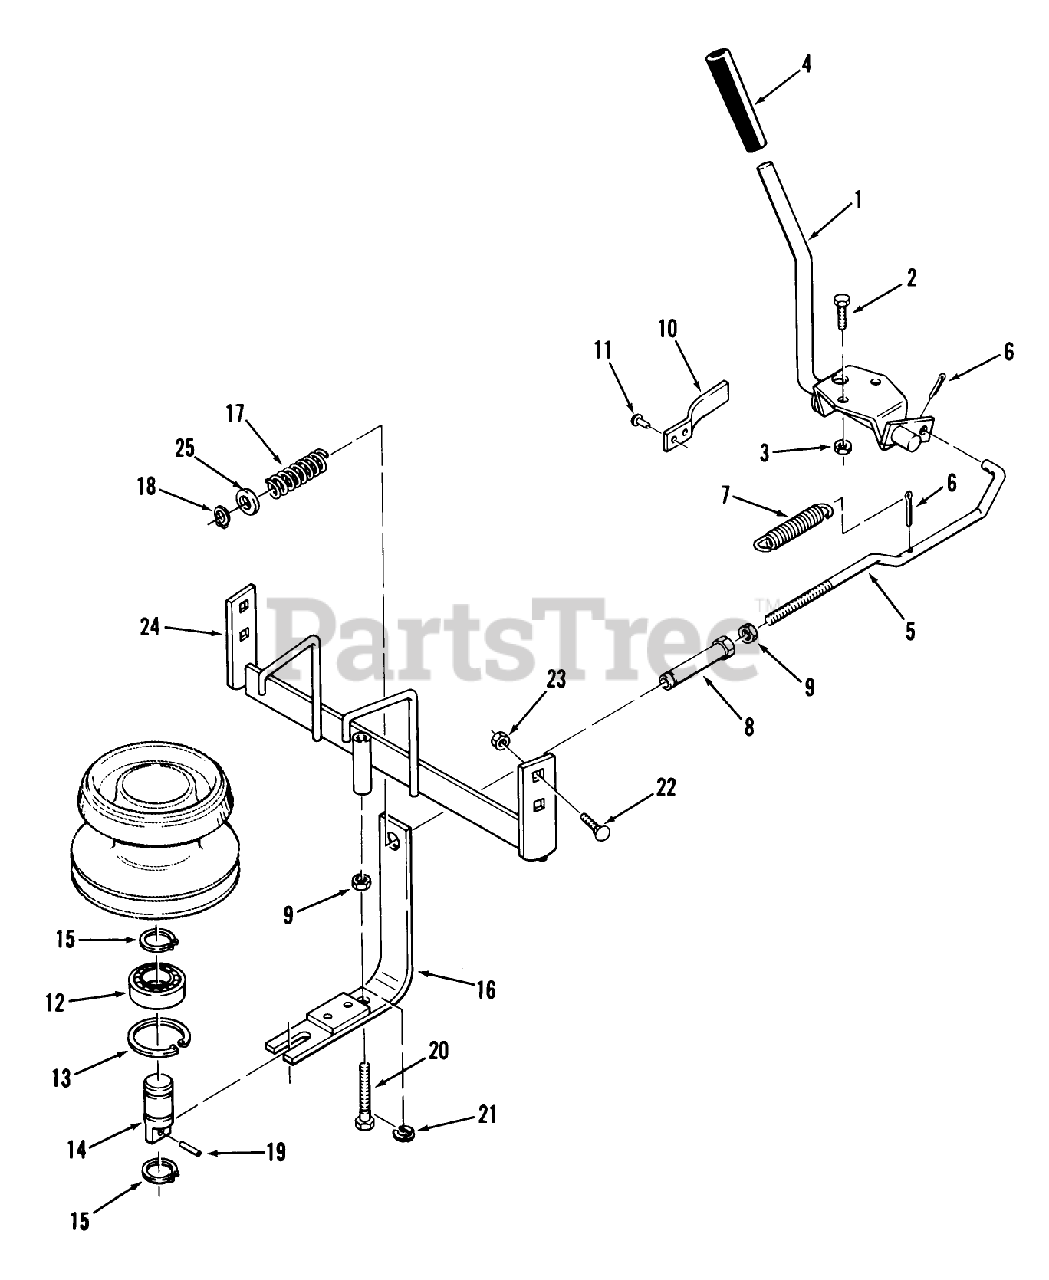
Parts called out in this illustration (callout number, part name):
1	PTO Clutch Lever
2	Bolt
3	Nut
4	GRIP
5	PTO Clutch Rod
6	Cotter Pin
7	Spring
8	TUBE-CLUTCH SPACER
9	Jam Nut 5/16-18
10	SPRING
11	RIVET
12	BaIl Bearing
13	Ring-Snap
14	Shaft Clutch Hsg
15	RING-SNAP, EXTERNAL
16	ASSY-CLUTCH BRAKE R
17	SPRING-CLUTCH
18	Retaining Ring
19	SPIROL PIN 7/32X7/8
20	SCREW-CLUTCH ADJUST
21	E-Ring
22	Bolt
23	Nut
24	BRACKET ASSY R
25	Washer
